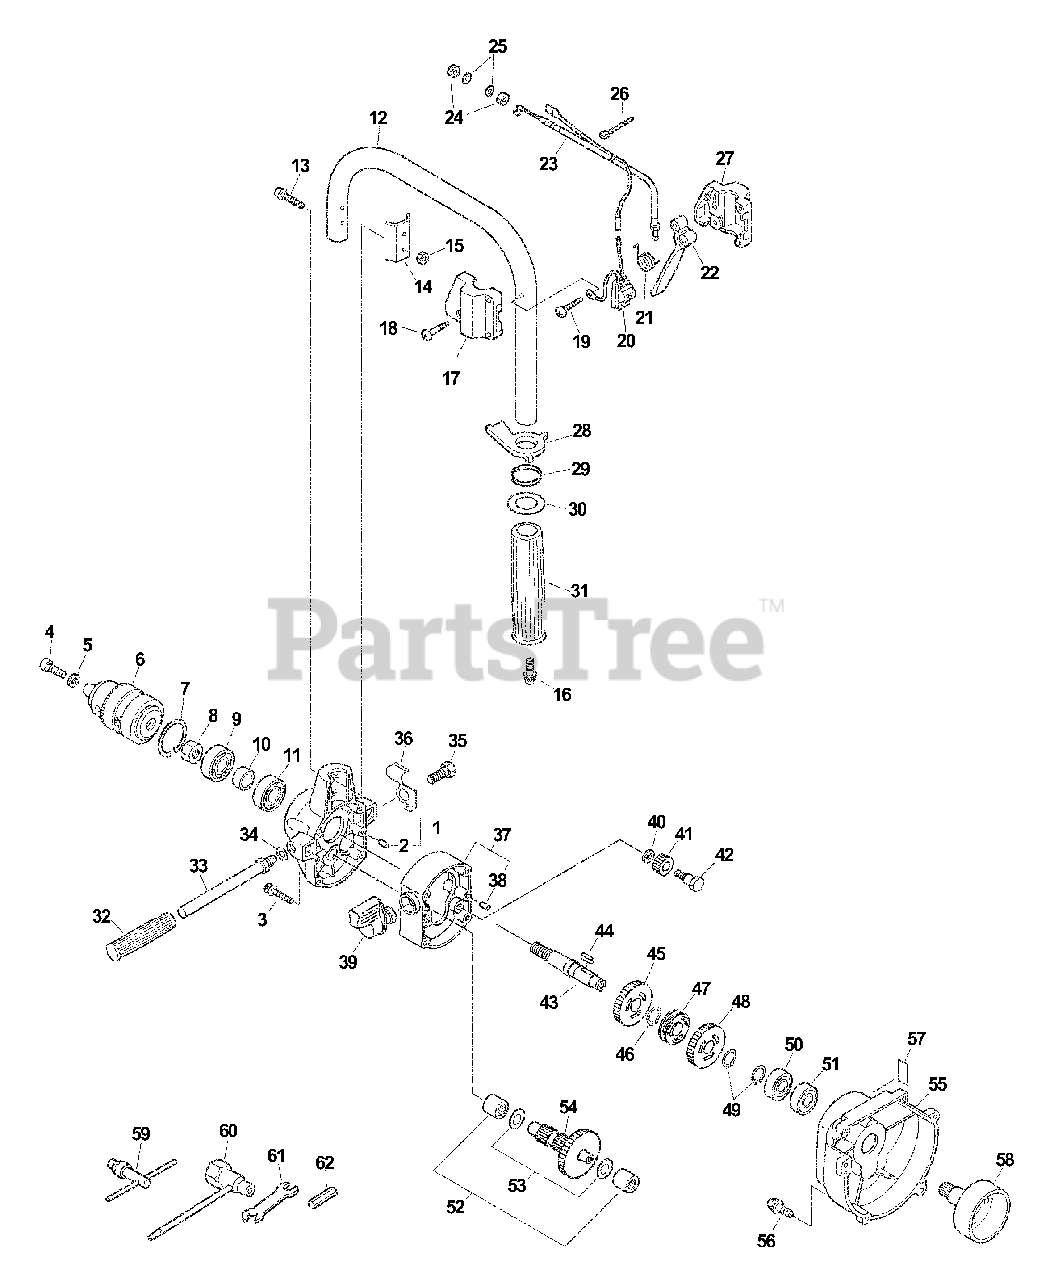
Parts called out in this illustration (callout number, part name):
1	HOUSING, GEAR CASE
2	PIN, LOCATING 4
3	BOLT 5×50
4	BOLT 6×20
5	WASHER 6
6	CHUCK, KEYED
7	RING, SNAP Ø32
9	BEARING, BALL 6002 DDU
11	BEARING, BALL 6002
13	BOLT M5×35
15	NUT, LOCK M5
16	SCREW 5×16
17	BRACKET, THROTTLE CONTROL - LEFT
18	SCREW 4×25
19	SCREW 4×30
20	SWITCH, ON-OFF
21	SPRING, THROTTLE RETURN
22	CONTROL, THROTTLE
23	CONTROL CABLE ASSY
25	WASHER 6.5×11.5×0.8
26	TIE, CABLE
27	BRACKET, THROTTLE CONTROL - RIGHT
28	LOCKOUT, THROTTLE
29	SPRING, THROTTLE LOCKOUT
31	GRIP, HANDLE
32	GRIP
33	HANDLE, LEFT
34	WASHER 10.5×18×1.6
35	BOLT 10×1.5×15
36	HOLDER, CHUCK KEY
37	CASE, GEAR
38	PIN, LOCATING 4
39	LEVER, CLUTCH
40	WASHER 6
41	GEAR, SPUR
42	BOLT, CLUTCH
43	SHAFT, AXLE
44	KEY, WOODRUFF 4×16
45	GEAR, SPUR
46	RING, RETAINING 15
47	NAIL, CLUTCH
48	GEAR, SPUR
49	RING, RETAINING - 12
50	BEARING, BALL 6001
51	BEARING, BALL 6001
52	BEARING, NEEDLE
54	GEAR, SHAFT
55	COVER, FAN
56	SCREW 4×16
57	LABEL, CAUTION
58	DRUM, CLUTCH
59	KEY, CHUCK
60	T-WRENCH 10×19 MM
61	SPANNER 17×19
62	BAR, HEX
